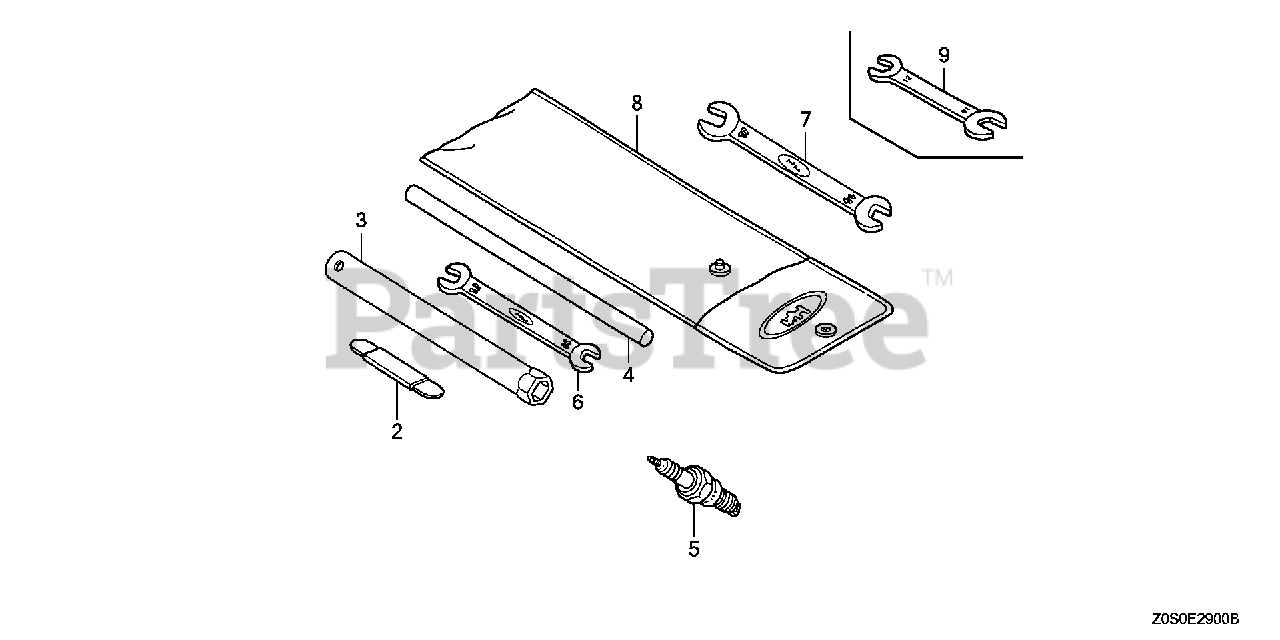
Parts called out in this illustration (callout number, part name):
2	GAUGE ASSY., THICKNESS
3	WRENCH, SPARK PLUG
4	HANDLE, BOX WRENCH
6	SPANNER (10X12)
7	SPANNER (14X17)
8	BAG, TOOL (230MM)
